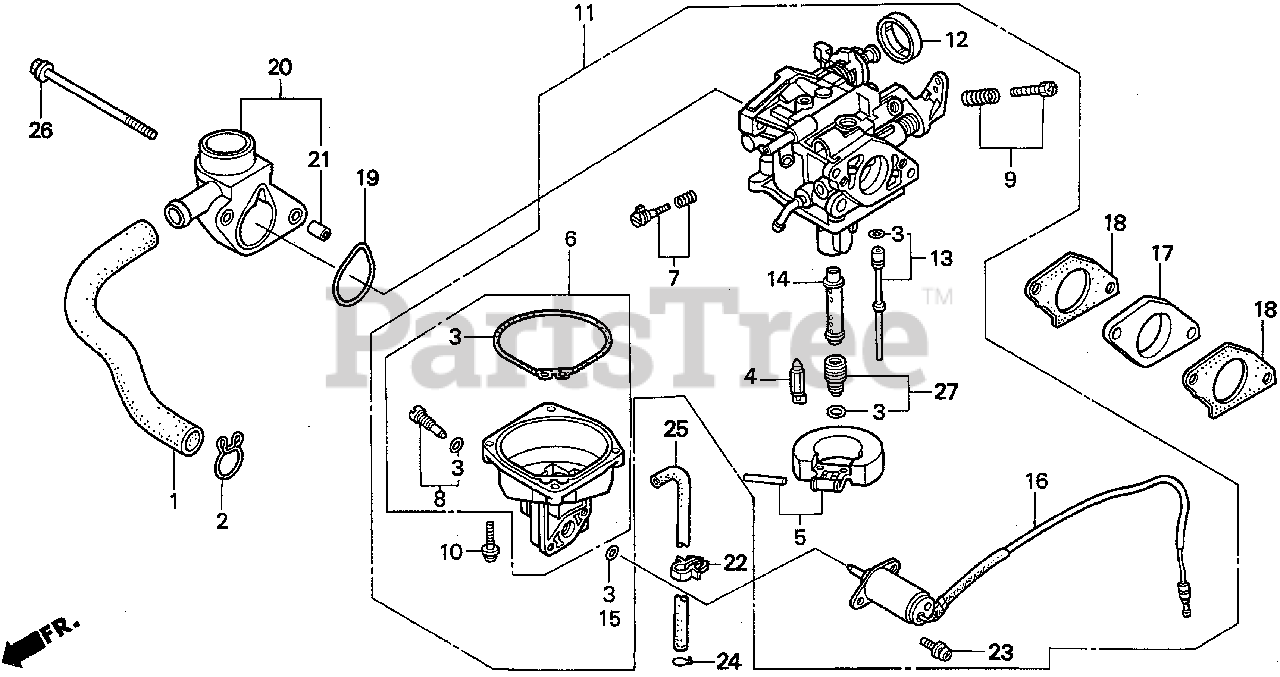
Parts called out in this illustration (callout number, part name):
1	TUBE, BREATHER
2	CLIP, BREATHER TUBE
3	GASKET SET
4	VALVE SET, FLOAT
5	FLOAT SET
6	CHAMBER SET, FLOAT (CARBURETOR NO.)
7	SCREW SET
8	SCREW SET, DRAIN (ADVENTURE GREEN) (CARBURETOR NO.)
9	SCREW SET
10	SCREW-WASHER
11	CARBURETOR ASSY. (BG22C A)
11	CARBURETOR ASSY. (BG22C B)
12	CAP, CHOKE LEVER DUST
13	JET SET (#55) (CARBURETOR NO.)
14	NOZZLE, MAIN (CARBURETOR NO.) (NOT AVAILABLE)
15	O-RING (5.8X1.9)
16	VALVE ASSY., SOLENOID (CARBURETOR NO.)
17	INSULATOR, CARBURETOR
18	GASKET, CARBURETOR
19	GASKET, AIR CLEANER
20	ELBOW, AIR CLEANER
21	COLLAR, DISTANCE
22	CLIP B, CABLE
23	SCREW-WASHER (5X12)
24	CLIP, TUBE (B8)
25	BULK HOSE, VACUUM (4.5X1000) (4.5X450) (BULK HOSE 95005-45008-10M)
26	BOLT, FLANGE (6X105)
27	JET SET, MAIN (#90)
27	JET SET, MAIN (#92) Use from Engine SN BG17A B.
27	JET SET, MAIN (#95)
